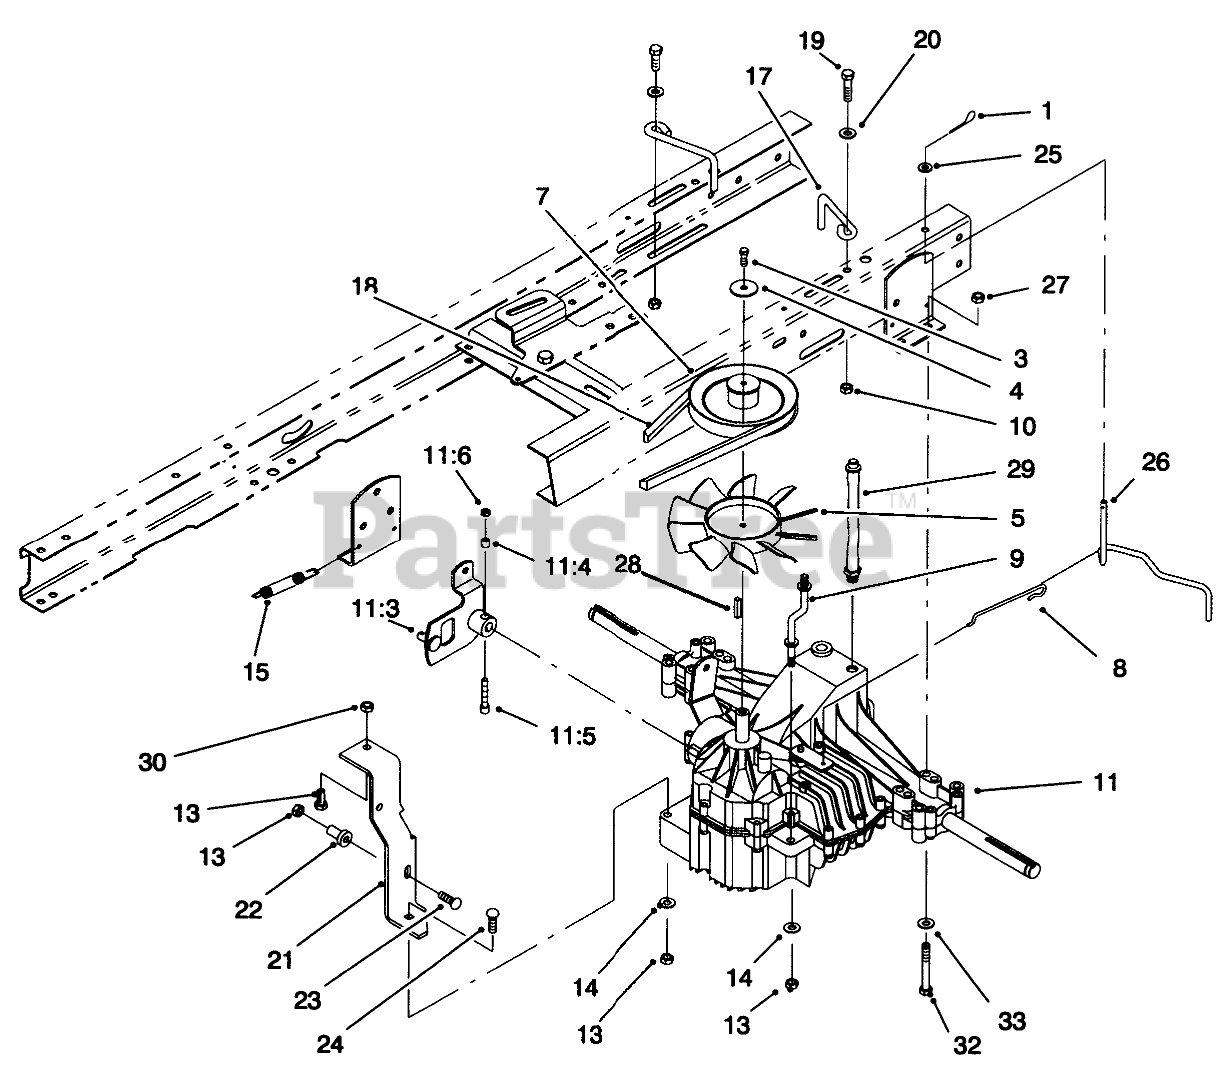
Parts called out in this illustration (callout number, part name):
1	PIN-COTTER
3	SCREW-HH
4	WASHER-FLAT
5	FAN - 10 BLADE 7" DIA.
7	PULLEY, TRANSMISSION
8	WIRE - BYPASS
9	STRAP - TORQUE
10	NUT-LOCK, NI
11	ASM-TRANSAXLE HYDRO 1644
11:3	WA - SPEED CONTROL LEVER
11:4	LOCK SPACER
11:5	SCREW-HSH
11:6	NUT-LOCK, NI
13	NUT-LOCK, NI
14	WASHER-PLAIN
15	SPRING-RETURN, BRAKE
16	SCREW-HH
17	GUIDE-BELT, TRANSMISSION
18	V-BELT, HYDRO
19	SCREW-HH
20	WASHER-PIVOT
21	Bracket-Speed Control
22	BUSHING-FLANGE
23	SCREW-CARR
24	BOLT-CARR
25	WASHER-FLAT
26	LEVER - BYPASS
27	NUT-LOCK, NI
28	KEY-PUMP
29	ASM - BREATHER HOSE
32	SCREW-HH
33	WASHER-PLAIN
